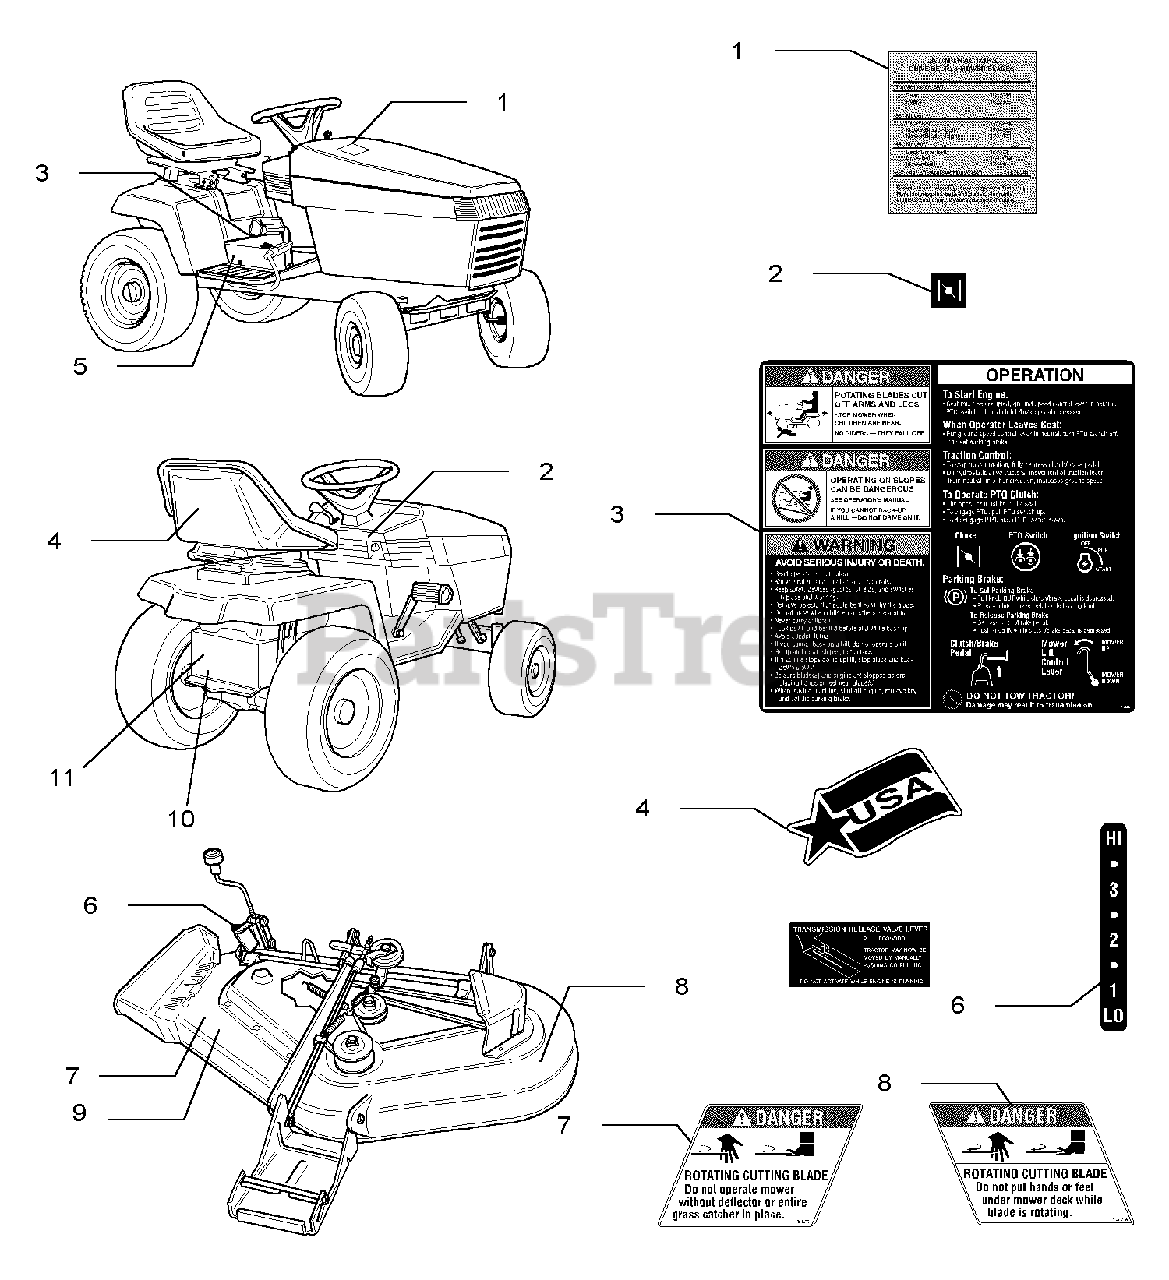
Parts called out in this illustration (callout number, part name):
1	DECAL, Belt, Blade
2	DECAL, Choke, Dash (Kohler Models Only)
3	DECAL, Operating Instructions
4	DECAL, USA Logo
5	DECAL, Transmission Release Valve
6	DECAL, Mower Height
7	DECAL, Danger (Chute in place)
8	DECAL, Danger (Hand under deck)
9	DECAL, Cutting Width 38"
9	DECAL, Cutting Width 44"
9	DECAL, Cutting Width 50"
10	DECAL, OPEI (Not serviced)
11	I.D. PLATES (Not serviced)
